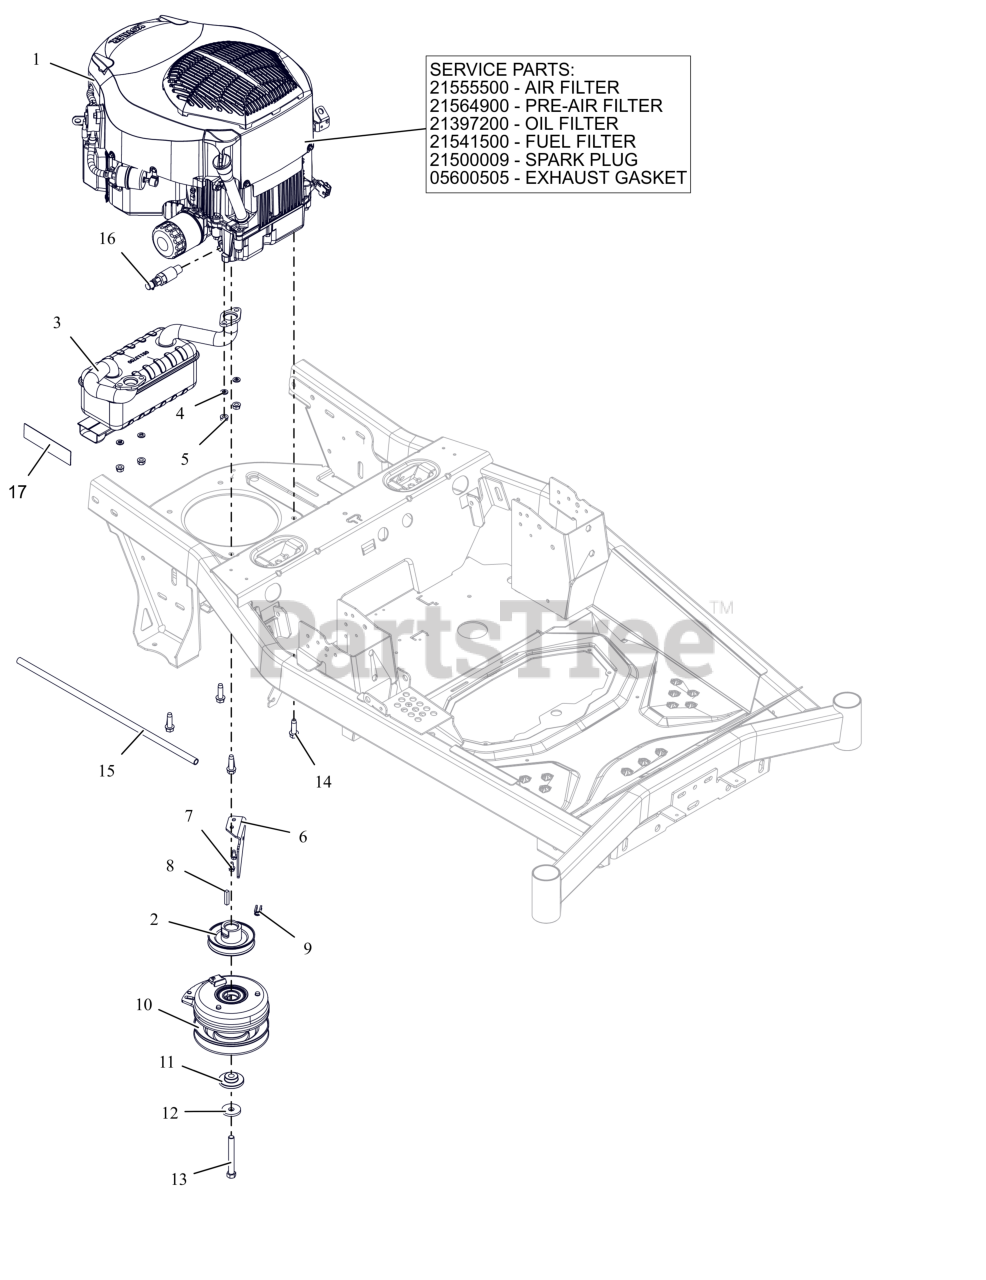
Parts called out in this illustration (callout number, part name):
1	ENGINE, KOHLER - KT730
1	AIR CLEANER, KOHLER
1	PRE-CLEANER, KOHLER
1	FILTER, OIL - KOH CV20
1	FILTER, FUEL
1	PLUG, SPARK KOHLER
1	GASKET, MUFFLER KOHLER TWIN
2	WLDMT-PULLEY-4.831OD X1.003
3	MUFFLER, KOHLER
4	WSHR,LK-REG .312X.078 ZCC
5	NUT-LK-TOP-FLG .312-18 GF ZCC
6	BRKT- CLUTCH STOP
7	SCR-TAP .25-20X.50 HWH ZCC
8	KEY-SQ .25 X 1.25 X .25 SAE
9	BSHG, CLUTCH
10	CLUTCH, WARNER-IXR-18211
11	BSHG-FLG .469X1.06X.574X2.0
12	WASHER, 7/16" SPRING DISK
13	BLT- HEX .44-20X3.50 G8 ZCC NT
14	SCR,TAP .375-16X1.25HWH TR ZCC
15	HOSE- OIL DRAIN
16	DRAIN, OIL
17	TAPE, HEAT
